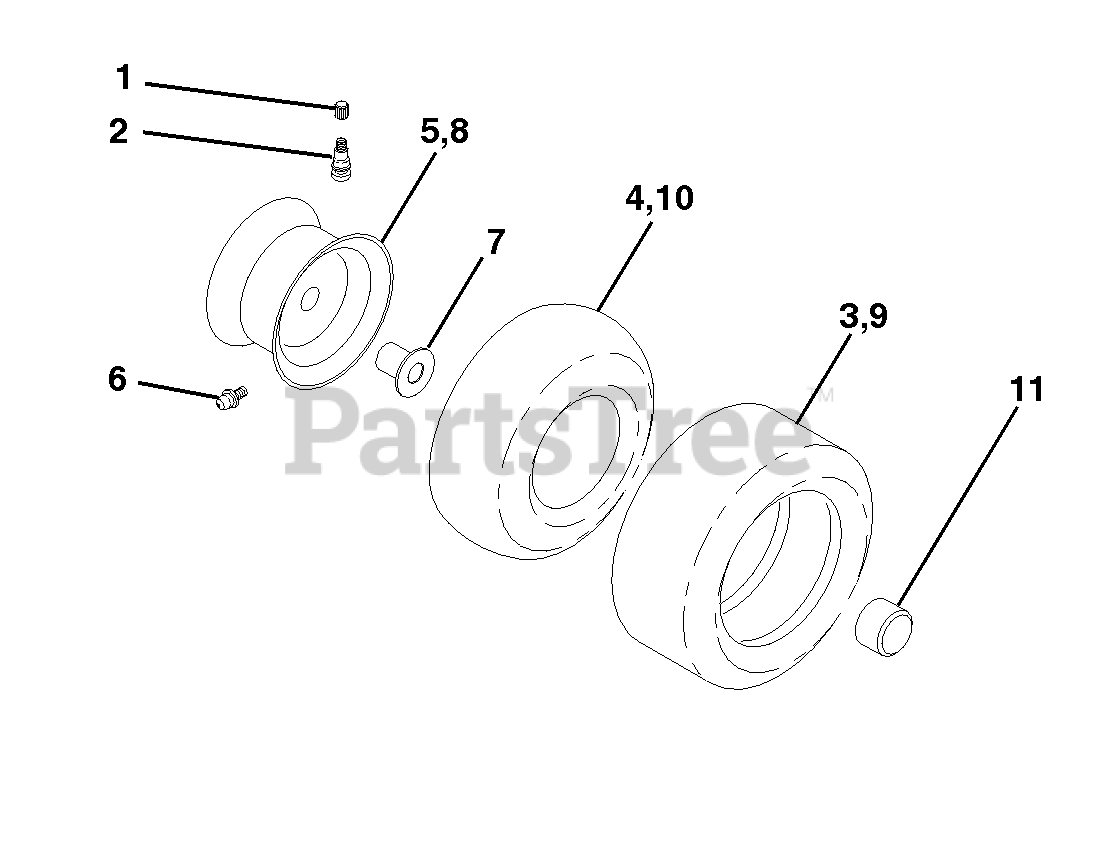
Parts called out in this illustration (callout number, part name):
1	Cap Valve Tire
2	Stem Valve
3	Tire F Ts 15 X 6 0 - 6
4	Tube Front
5	Rim Asm 6" front Silver
6	Fitting Grease
7	Bearing Flange
8	Rim Asm 8" rear Silver
9	Tire R Ts 18 x 8 5-8 C
10	Tube Rear
11	Cap Axle Blk 1 50 X 1 00
